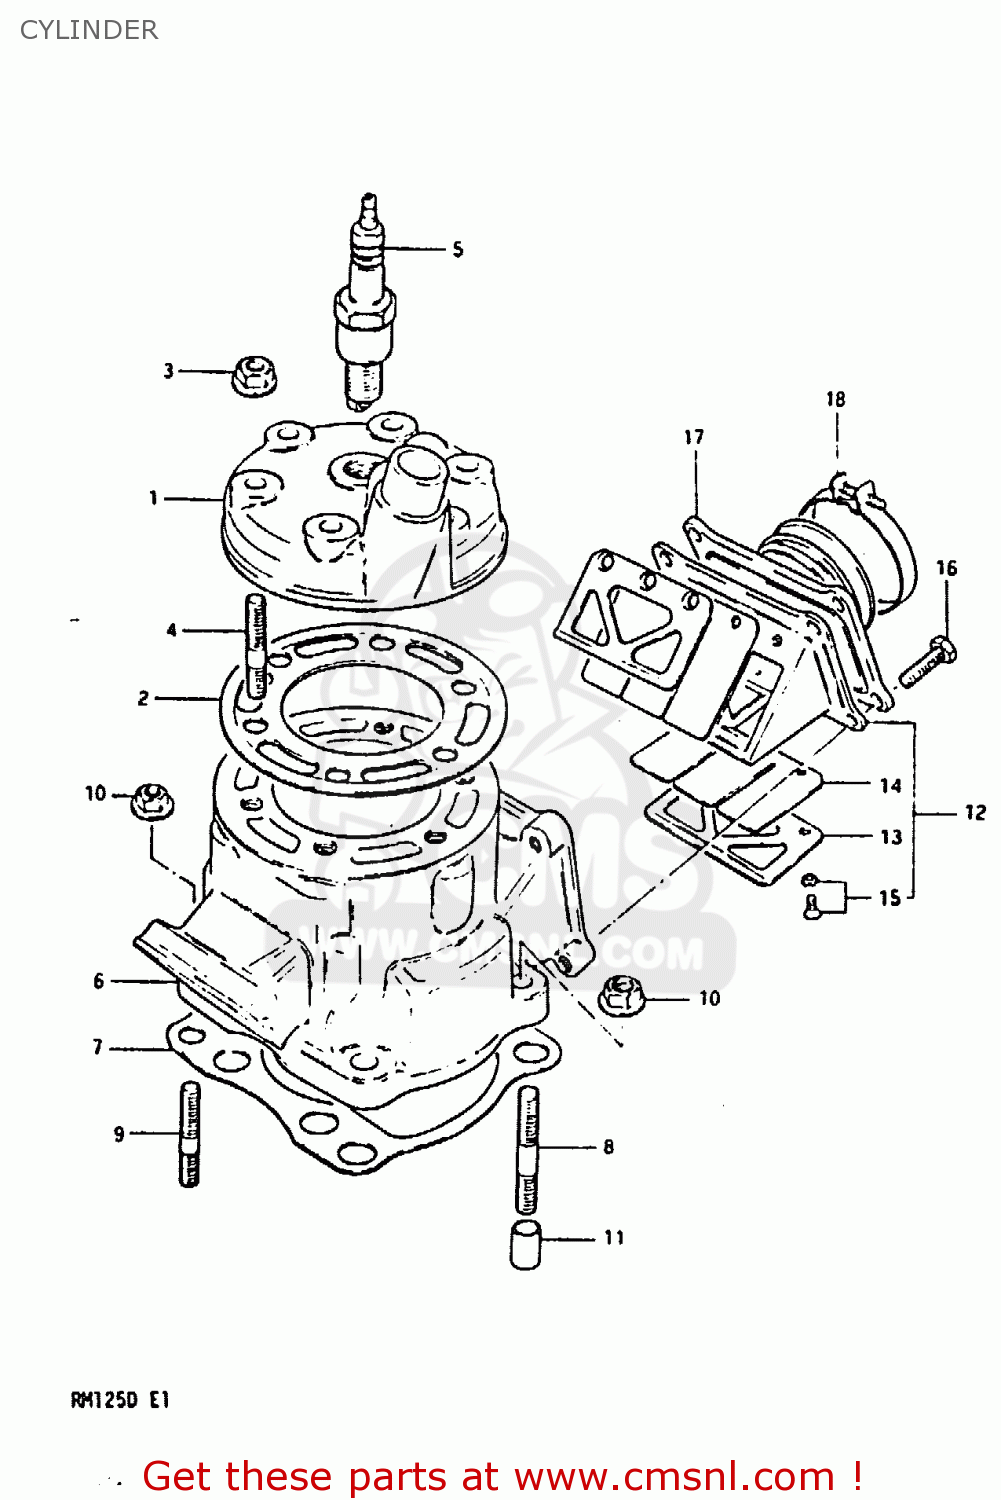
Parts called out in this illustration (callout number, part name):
1	HEAD,CYLINDER.
2	GASKET,CYLINDER HEAD (MCA)
3	NUT 8MM
4	STUD
5	SPARK PLUG
6	CYLINDER
7	GASKET,CYLINDER (MCA)
8	STUD
9	STUD
10	NUT 8MM
11	PIN
12	VALVE ASSEMBLY,REED
13	STOPPER,REED VALVE
14	VALVE,REED
15	SCREW
16	BOLT
17	PIPE,INTAKE
18	CLAMP
